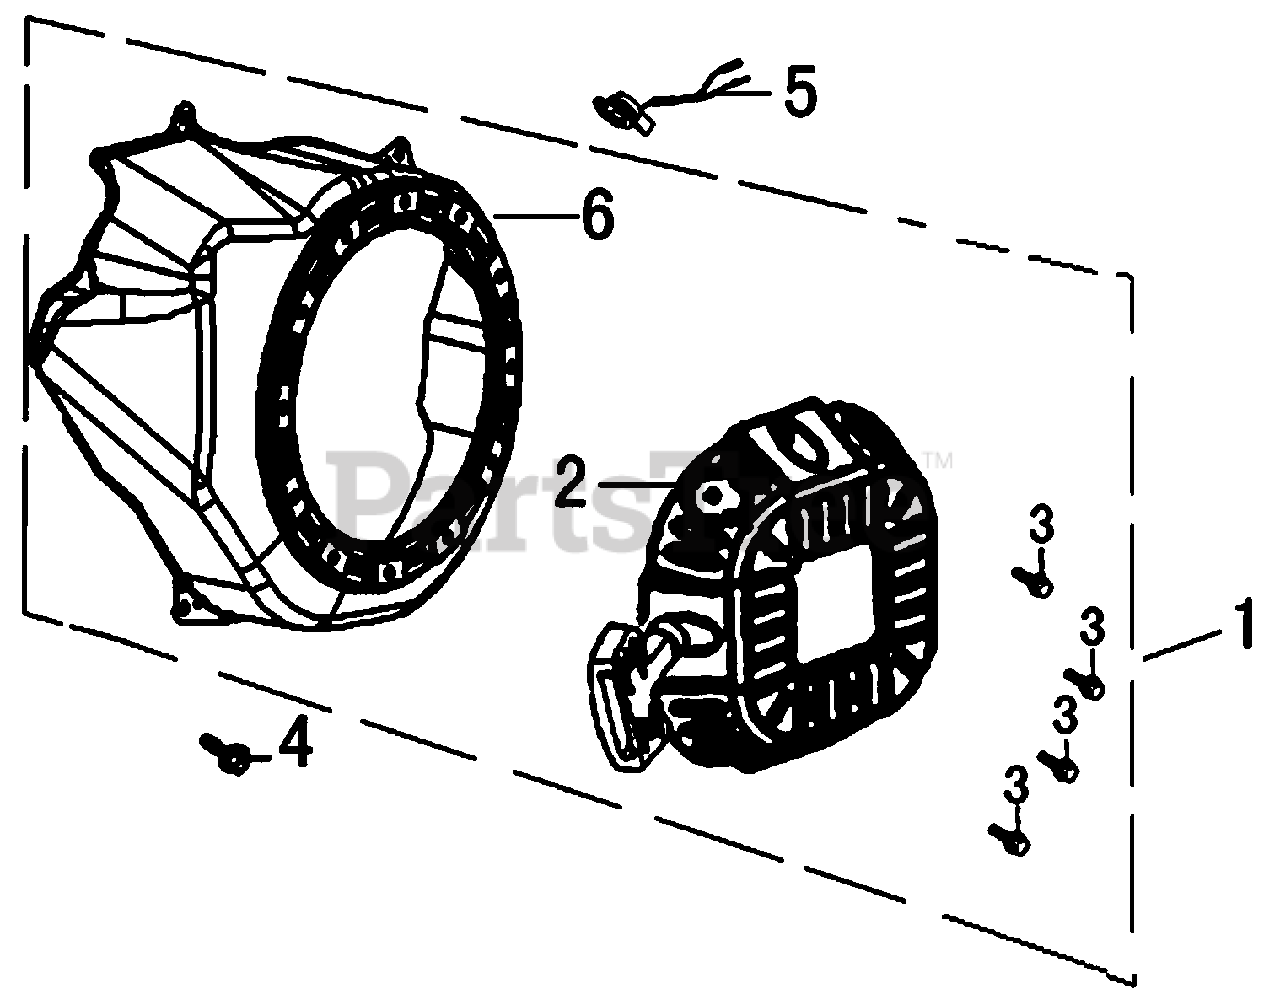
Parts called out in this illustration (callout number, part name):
1	RECOIL STARTER W/HSNG
2	STARTER ASSY., RECOIL
3	BOLT, FLANGE 6x8
4	BOLT, FLANGE 6x10
5	SWITCH ASSY., ENGINE STOP
6	COVER, FAN
